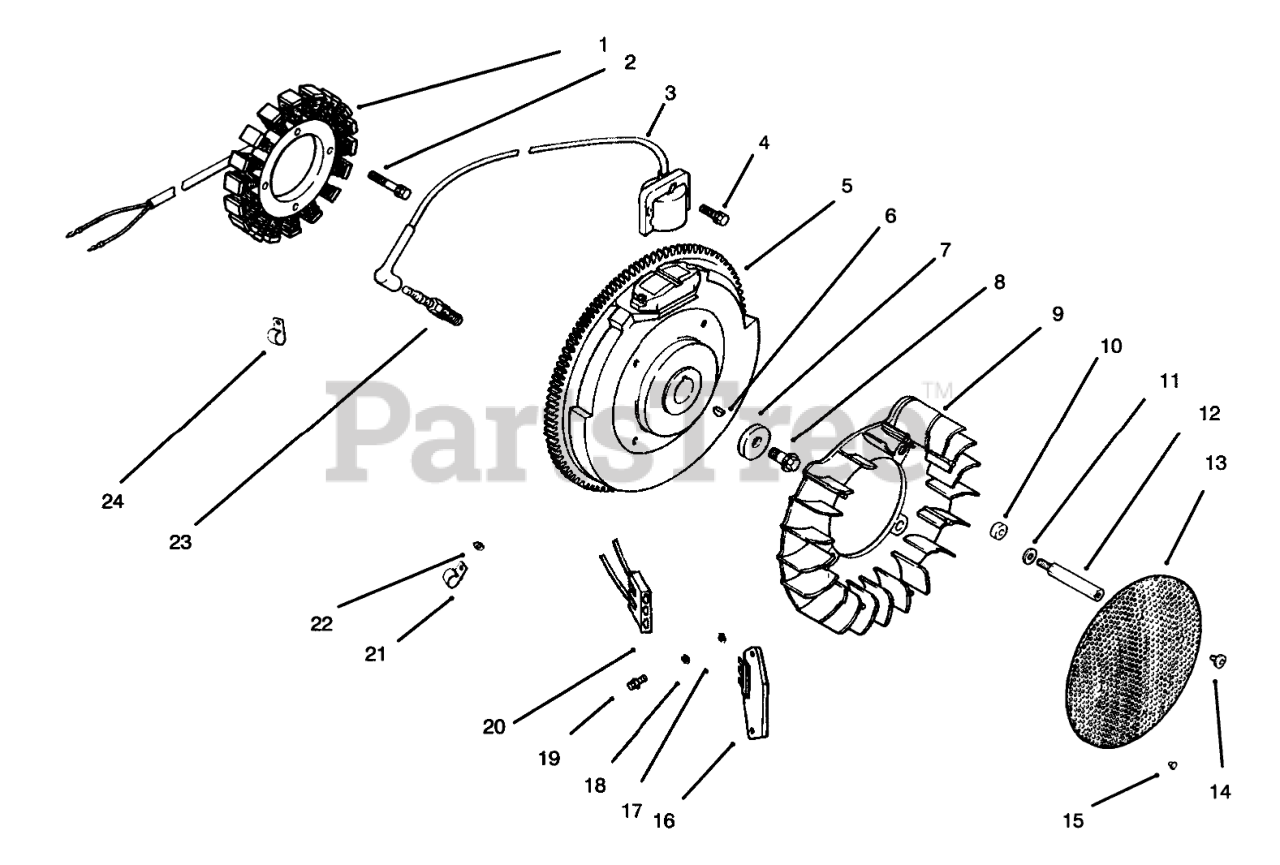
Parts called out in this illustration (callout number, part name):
1	Stator-15 amp
2	Screw
3	Module-Ignition
4	Screw
5	Flywheel Assembly
6	Key
8	Screw
10	Spacer-Fan
11	Washer
12	Stud-Grass Screen
13	Screen-Grass
14	Screw
16	Rectifier-Regulator
17	Washer
18	Washer
20	Connector
21	Clip
22	Washer
23	Spark Plug
